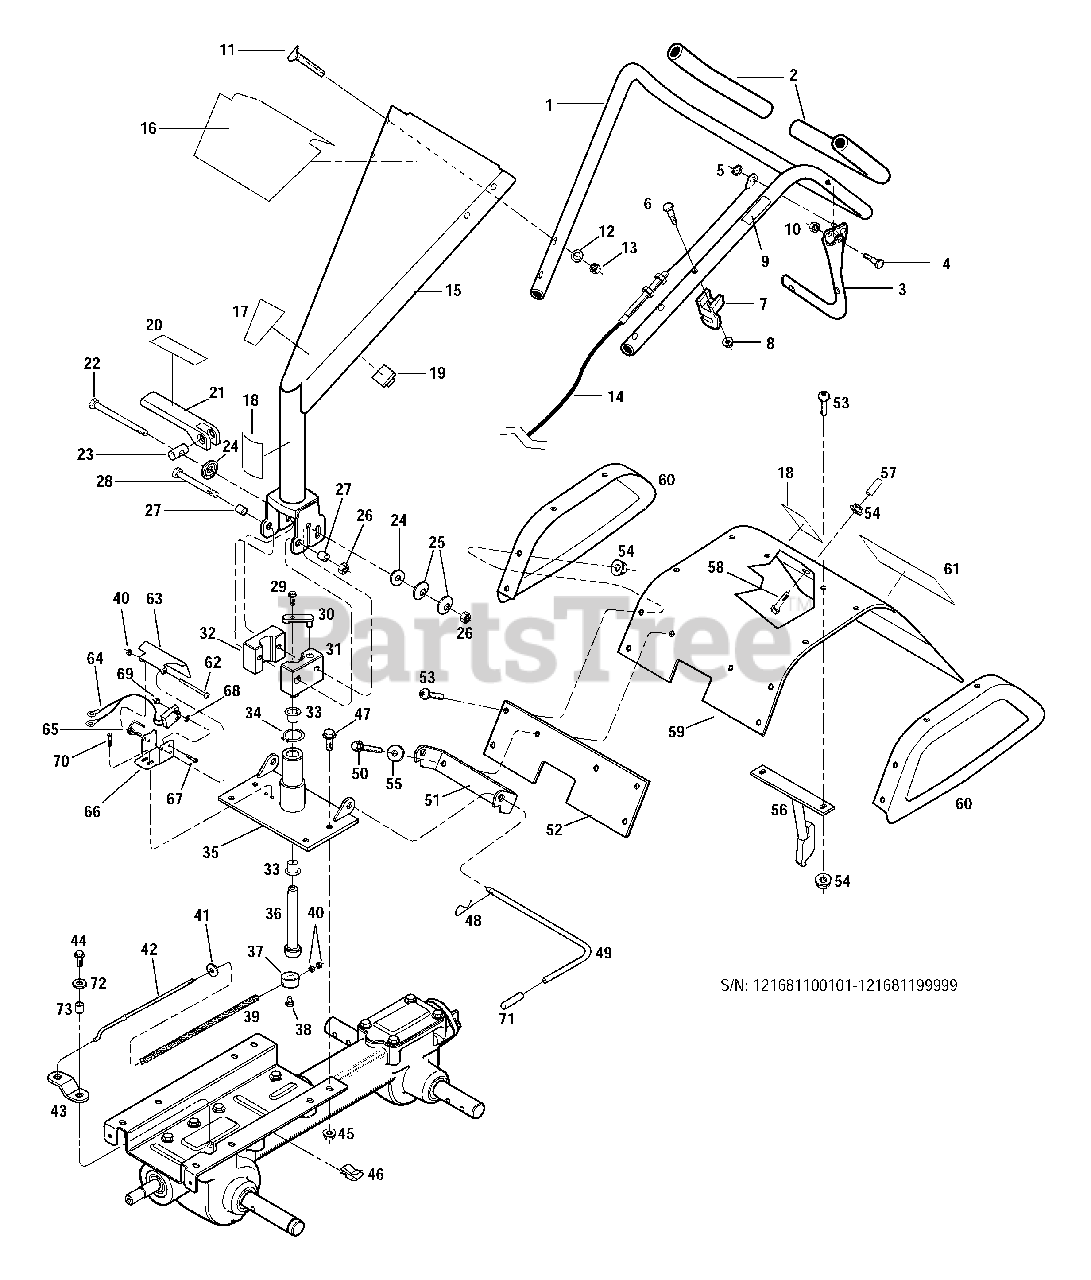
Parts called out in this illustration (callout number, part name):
1	Upper Handlebar
2	Upper Handlebar Foam Grip
3	Bail-Control
4	Screw, 1/4-20 x 1-1/2
5	Ring-Grip, 1/4" ID
6	Screw, 1/4-20
7	Bracket, Cable
8	Hex Nut, 1/4-20
9	Decal, Bail
10	Hex Nut, 1/4-20 Nylon
11	Screw, Curved Head, 5/16-18 x 2
12	Washer, Springlock
13	Hex Nut, 5/16-18
14	Control Cable
15	Lower Handlebar
16	Decal, Handlebar Logo/Instruction
17	Decal, Horsepower
18	Decal, Tine Warning
19	Cord Clip
20	Decal, Locking Lever
21	Locking Lever
22	Locking Bolt, 3/8-16 x 4-1/4
23	Pivot
24	Washer-Heat Treated
25	Washer-Belleville
26	Hex Nut, 3/8-16, Nylock
27	Bushing, 1/2" Dia
28	Screw, Hex Head, 3/8-16 x 3-1/4
29	Screw, 1/4-20 x 5/8 Self-Tapping
30	Engage/Disengage Arm
33	Nylon Bushing
34	Retaining Ring-External
35	Base Plate Weldment
37	Linkage Rod Holder
38	Bolt, 1/4 x 3/4
39	Spring, Compression
40	Hex Lock Nut, #10-24
41	Washer, Flat, .188
42	Adjusting Rod
43	Lever, Wheel Drive
44	Hex Head Screw, 1/4-20 x 1/2
45	Hex Flange Lock Nut, 5/18-18
46	Wire Clip
47	Screw, Hex Flange Lock, 5/16-18 x 3/4
48	Hair Pin
49	Latch Pin
50	Screw, 1/4-20UNC-2A x 7/8
51	Front Latch-Hood
52	Hood Reinforcement Plate
53	Screw, Button Head, 1/4-20 x 1/2
55	Washer-Flat
56	Rear Post Weldment
57	Bumper, Caplug
58	Screw, Hex Head, 1/4-20 x 1-1/4
59	Hood Assembly
60	Hood Side
61	Decal, Hood Logo
62	Screw, #10-24 x 2-1/4
63	Cover-Switch
64	Switch-Interlock
65	Spring, Switch
66	Base-Switch
67	Screw, Hex Head, #6-32 x 3/4
68	Washer, Flat, #6
69	Nut, Sems, #6-32
70	Screw, Hex Flange, #10-32
71	Grip, Handle
72	Washer, Flat, 1/4
73	Spacer, 7/16 ID x 3/8 Lg
